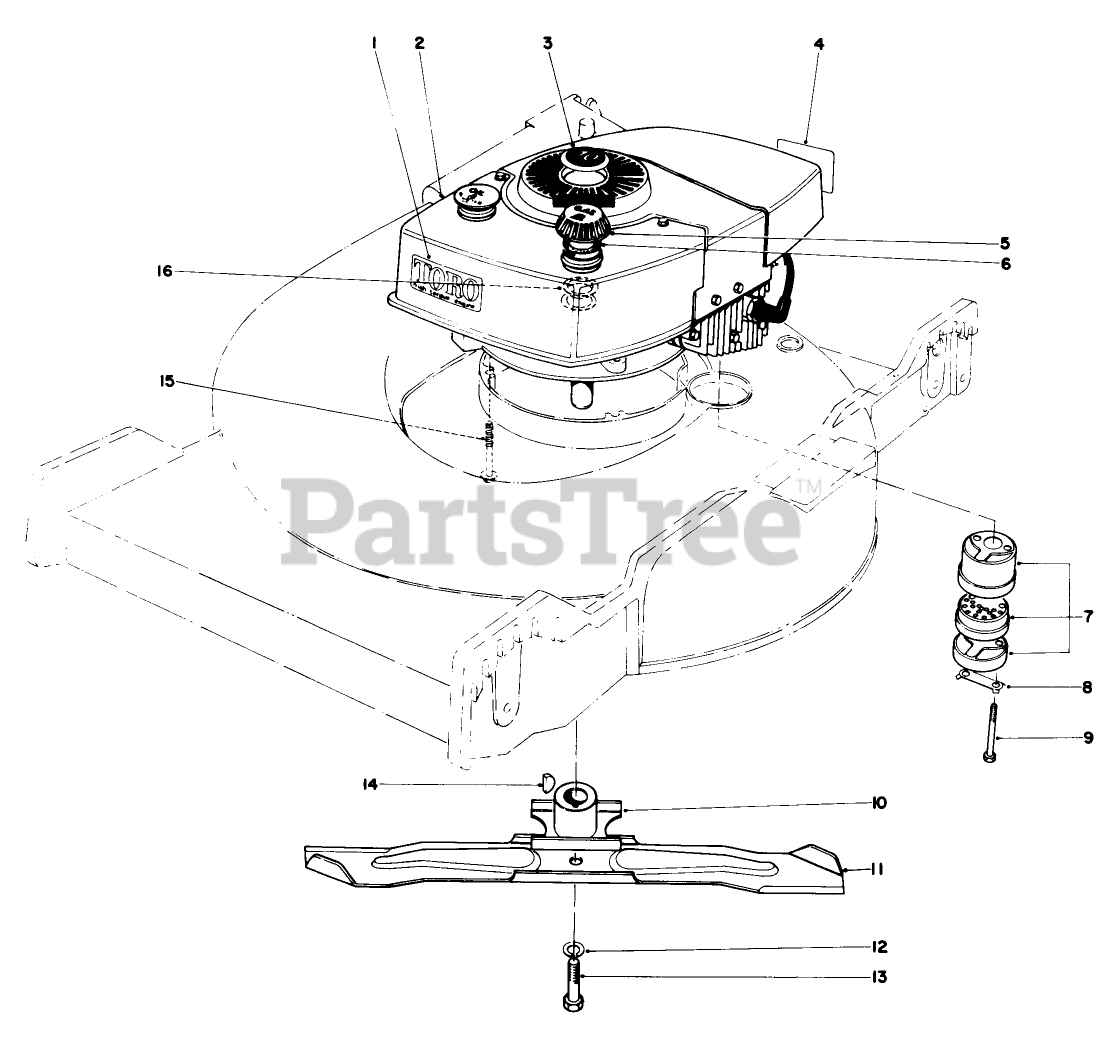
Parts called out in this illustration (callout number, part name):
1	High Torque
2	Engine
3	PLUG BUTTON
4	Decal Maintenance
5	Gas Cap (Incl. Ref. #6 & 16)
6	GASKET
7	Muffler Assembly (Incl. Ref. #8 & 9)
8	CLIP - LOCKING
9	SCREW-HH
10	BLADE RETAINER WA(BLACK)
11	Blade
12	WASHER-LOCK
13	BLADE SCREW
14	KEY-WOODRUFF
15	3/8-16 X 2-3/4 CAPSCR
16	GAS CAP BAFFLE
